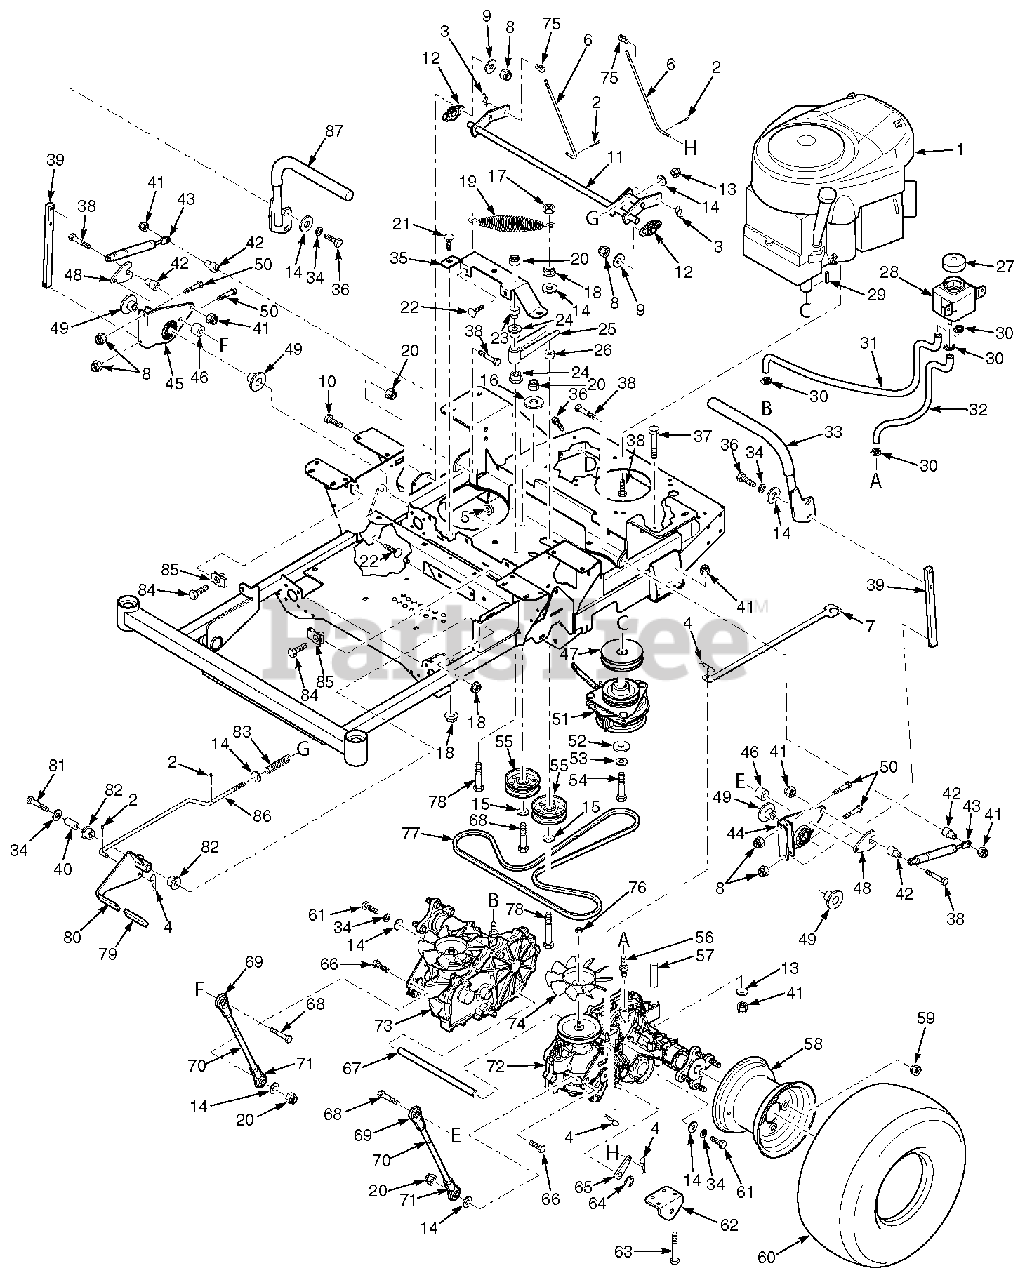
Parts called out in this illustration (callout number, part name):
1	Engine, Kawasaki 18FR
1	Engine, Kohler 22KT
1	Engine, Kawasaki 21FR
1	Engine, Kohler 24KT
2	Cotter Pin, 3/32 x 1"
3	Pin, Rue Cotter 3/8" Dia.
4	Hair Pin, .080 x 1.19"
5	Nut, Serrated Flange 5/16-18
6	Rod, Brake Adjustment
7	Lever, Dump Valve
8	Nut, Elastic Stop 1/4-20
9	Flatwasher, 1/4-.312 x .750 x .065
10	Bolt, Serrated Flange 1/4-20 x 1-1/4"
11	Weldment, Brake Lever
12	Bearing
13	Flatwasher, 5/16-.375 x .875 x .083
14	Flatwasher, 3/8-.391 x .938 x .105
15	Flatwasher, 3/8-.391 x .938 x .105 HD
16	Flatwasher, 3/8-.406 x 1.5 x 7 GA.
17	Nut, Center Lock 3/8-16
18	Nut, Serrated Flange 3/8-16
19	Spring, Transmission Idler
20	Nut, Elastic Stop 3/8-16
21	Bolt, Carriage 3/8-16 x 3/4"
22	Bolt, Carriage 5/16-18 x 3/4"
23	Shaft Pivot, Idler Arm
24	Bearing
25	Transmission Idler Arm Assembly
26	Spacer, Idler Pulley
28	Reservoir Assembly
29	Key, 1/4 x 1/4 x 3/4"
30	Clamp, 0.87" Max Dia.
31	Hose, RH Transmission
32	Hose, LH Transmission
33	Handle Bar Assembly LH, w/Grip
34	Flatwasher, 3/8-.391 x .938 x .105
35	Support, Idler Arm
36	Bolt, Hex Head 3/8-16 x 1"
37	Bolt, Hex Head 5/16-18 x 5"
38	Bolt, Hex Head 5/16-18 x 1-1/2"
39	Bar, Control Lever
40	Pivot, Brake Lever
41	Nut, Elastic Stop 5/16-18
42	Spacer, Pump Dampener
43	Dampener
44	Control Link, LH
45	Control Link, RH
46	Spacer
47	Pulley, 4-1/2" Dia. 1" Bore
48	Nut, Control Linkage
49	Spacer, Linkage
50	Bolt, Hex Head 1/4-20 x 1-1/2"
51	Electric Clutch Assembly
52	Flatwasher, 7/16-.469 x 1.75 x .25
53	Lockwasher, 7/16" spring
54	Bolt, Hex Head 7/16-20 x 2-1/4" Patch
55	Pulley, 3-1/2" Dia.
56	Fitting, Transmission
57	Spacer, Axle
58	Rim w/Valve Stem
59	Wheel Nut, 1/2-20
60	Wheel Assembly
60	Tire, 20 x 10-8 2-Ply
61	Bolt, Hex Head 3/8-16 x 2-1/4"
62	Bracket, Pusharm Link
63	Bolt, Hex Head 5/16-18 x 3"
64	Clip, Brake Lever
65	Lever, Brake
66	Bolt, Hex Head 3/8-16 x 1-1/4"
67	Spacer, Axle
68	Bolt, Hex Head 3/8-16 x 2"
69	Rod End, 3/8-24 LH
70	Linkage, Pump
71	Roc End, 3/8-24 RH
72	Transaxle Assy., LH
73	Transaxle Assy., RH
74	Fan
75	Joint, Swivel
76	Fan Nut
77	Belt, Transmission Drive
78	Bolt, Hex Head 3/8-16 x 3"
79	Grip, Brake Handle
80	Brake Handle Assembly
81	Bolt, Hex Head 3/8-16 x 2-1/2"
82	Bearing
83	Spring, Brake
84	Bolt, Hex Head 3/8-16 x 1-1/4" Special Lock
85	U-Nut, 3/8-16
86	Rod, Brake Linkage
87	Handle Bar Assembly RH, w/Grip
